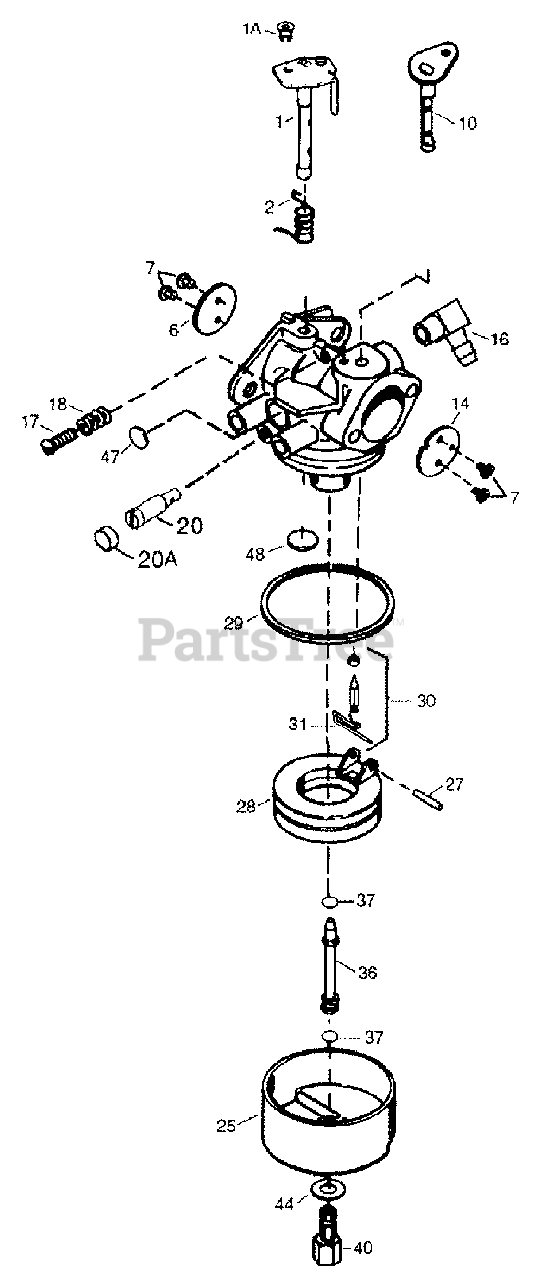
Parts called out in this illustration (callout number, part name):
1	Throttle Shaft & Lever Assembly
2	Throttle Return Spring
6	Throttle Shutter
7	Shutter Screw
10	Choke Shaft & Lever Assembly
14	Choke Shutter
15	Choke Positioning Spring
16	Fuel Fitting
17	Throttle Crack Screw/Idle Speed Screw
18	Tension Spring
20	Idle Restrictor Screw
20A	Idle Restrictor Screw Cap
25	Float Bowl Assembly
27	Float Shaft
28	Float (Plastic)
29	Float Bowl "O" Ring
30	Inlet Needle, Seat, & Clip
31	Spring Clip
32	Bowl Drain Assembly
33	Drain Plunger Gasket
36	Main Nozzle Tube
37	O Ring, Main Nozzle Tube
40	High Speed Bowl Nut
44	Bowl Nut Washer
47	Welch Plug, Idle Mixture Well
48	Welch Plug, Atmospheric Vent
60	Repair Kit
